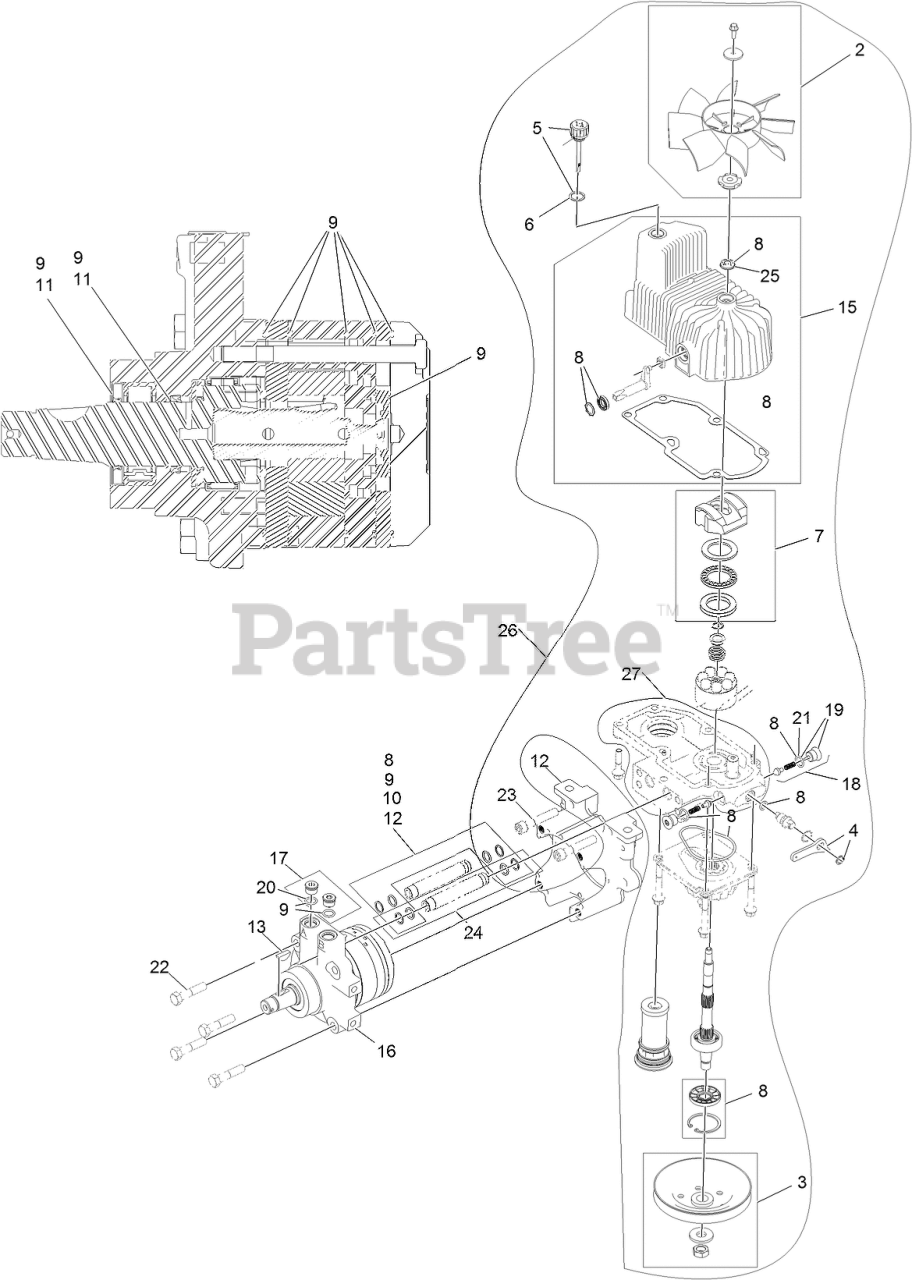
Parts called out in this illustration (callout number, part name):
2	FAN KIT
3	PULLEY KIT
4	HANDLE-BYPASS VALVE, HYDRO
5	DIPSTICK-HYDRO W/GASKET
6	GASKET-DIPSTICK, HYDRO
7	SWASH BLOCK KIT
8	PUMP SEAL KIT
9	MOTOR SEAL KIT
10	TUBE SEAL KIT
11	OUTPUT SHAFT SEAL KIT
12	NOSE CUP-UHT
13	KEY-WOODRUFF
15	HOUSING-HYDRO, LH
16	MOTOR-HYDRAULIC LH 240CC
17	MAGNETIC PLUGS SERVICE KIT
18	CHECK VALVE ASM
19	PLUG-CHECK (W/O-RING)
21	O-RING-CHECK VALVE
22	SCREW HH
23	SCREW-HSH
24	HYDRAULIC TUBE KIT
25	SEAL-FAN DRIVE
26	PULLER-PULLEY
27	PULLER-PULLEY
